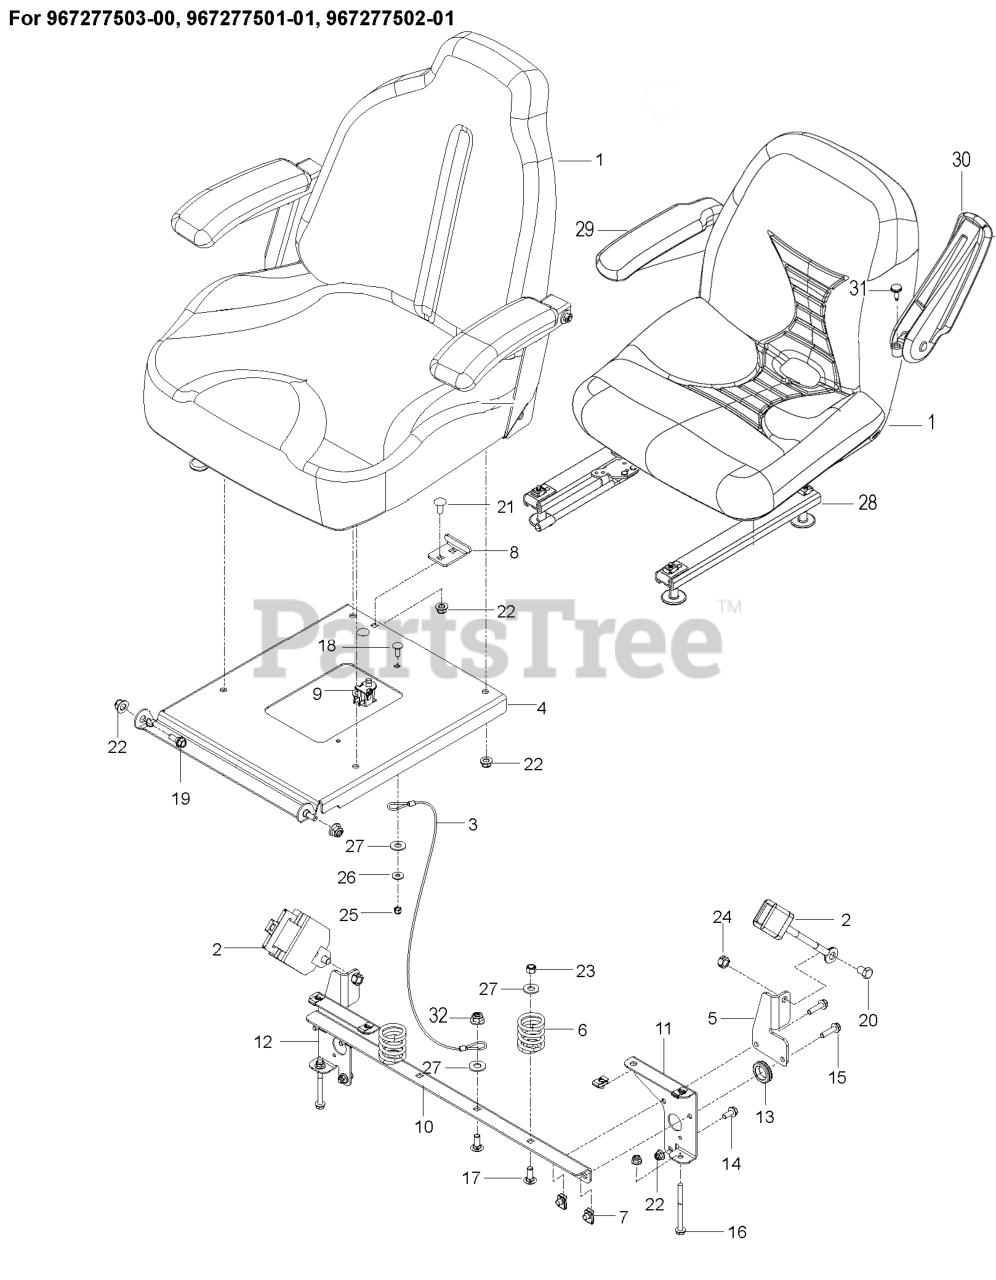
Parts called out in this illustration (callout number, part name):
1	SEAT.ASM.907.TRACK.W/O.BELT
1	SEAT
2	SEAT BELT, RETRACTABLE
3	SEAT LANYARD
4	SUPPORT.SEAT.ORANGE
5	MOUNT.SEAT.BELT.BLACK
6	SPRING.COMPRESSION.SEAT.BLACK
7	U-CLIP 5/16-18 NUT RETAINER
8	STOP, SEAT - BLACK
9	SEAT SWITCH
10	SUPPORT.SEAT. BLK
11	SUPPORT.RT.BLK
12	SUPPORT.LT.BLK
13	RUBBER GROMMET
14	HHFS 5/16-18 X 3/4
15	HHFS 5/16-18 X 1.25 TPBLT GD 5
16	BOLT.HEX.FLNG.5/16-18X3.75
17	BOLT D
17	RHSNB 3/8C X 1
18	BOLT
18	1/4-20X3/4 CARR BLT
19	SB 5/16-18 HEX HD GD5, BLK ZN
20	HCS 7/16-20 X .75 GD 5
21	RHSNB 5/16-18 X 3/4 GR5 BLK ZN
22	5/16-18 NYLOC FLANGE NUT
23	NUT
23	NUT 3/8-16 NYLOC
24	NUT HEX 7/16F LOCK RP
25	NUT.1/4-20.HEX.NYLOC.ZD
27	RP WASHER 3/8 FLAT
28	TRACK ADJUSTMENT KIT
29	ARMREST KIT, RT SQUARE END
30	ARMREST KIT, LT SQUARE END
31	ADJUSTER KNOB
32	NUT 3/8-16 HEX FLG NYLOC ZD
